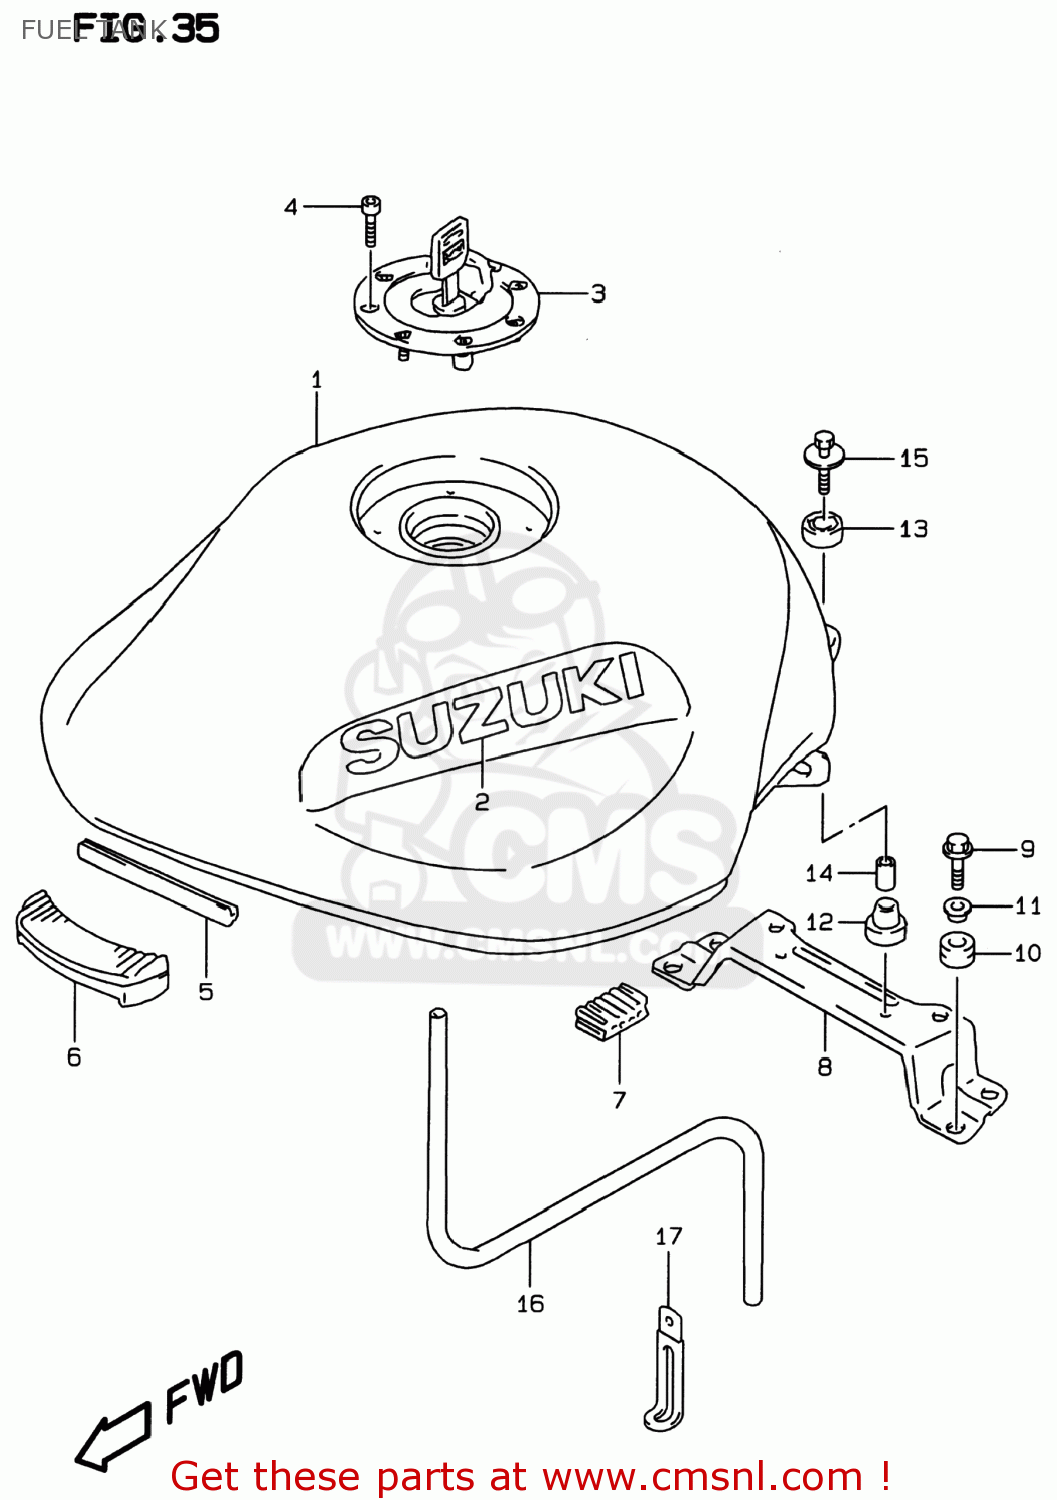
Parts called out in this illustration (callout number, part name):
1	TANK ASSEMBLY,FUEL
2	EMBLEM,FUEL TANK
3	CAP SET,FUEL
4	BOLT(5X20)
5	MOLDING
6	CUSHION,FUEL TANK FR
7	CUSHION,SEAT(40X20X15)
8	BRACKET,FUEL TANK RR
9	BOLT(6X25)
10	CUSHION
11	WASHER
12	CUSHION
13	CUSHION
14	SPACER(6.5X9X18)
15	BOLT(6X30)
16	HOSE(7X10.2X2000)
17	CLAMP(L:97)
